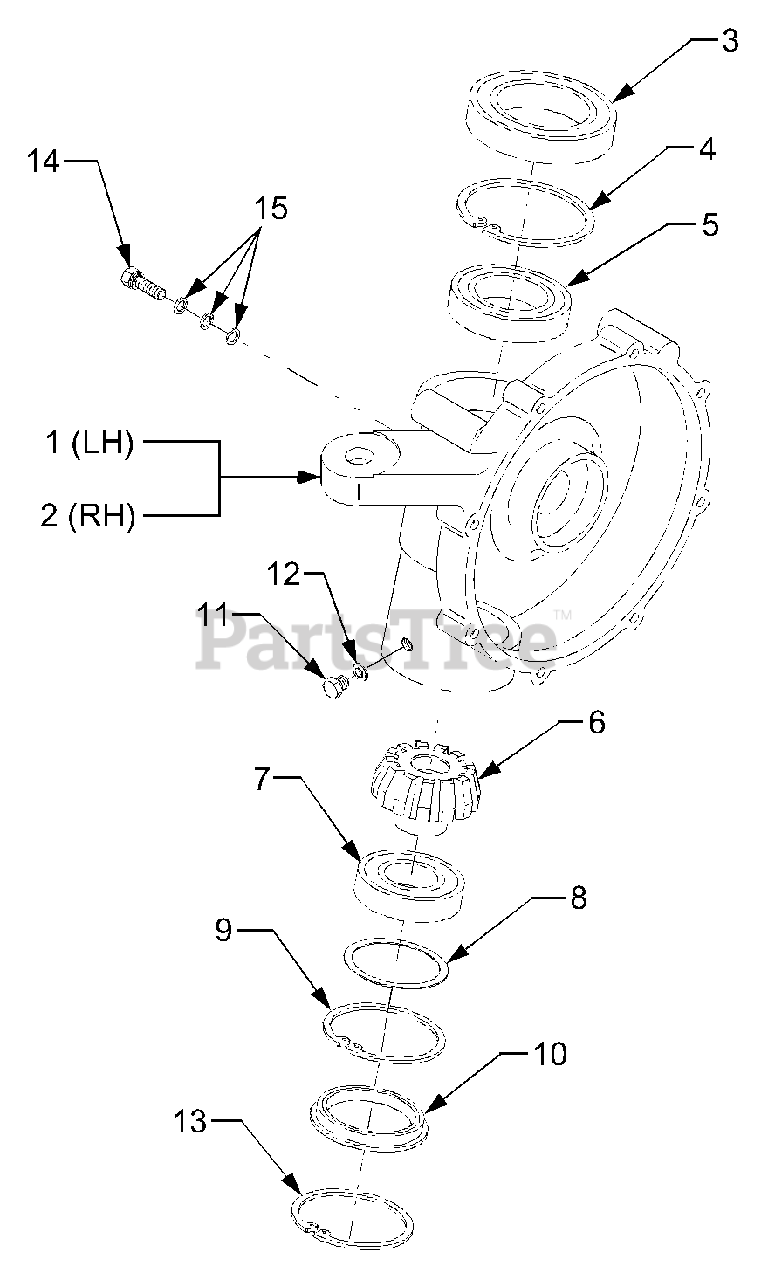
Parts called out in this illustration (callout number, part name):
1	Case, Front Axle(LH)
2	Case, Front Axle(RH)
3	Bearing, Ball
5	Bearing, Ball
6	Gear 13, Bevel
7	Bearing, Ball
15	Washer, Plain
